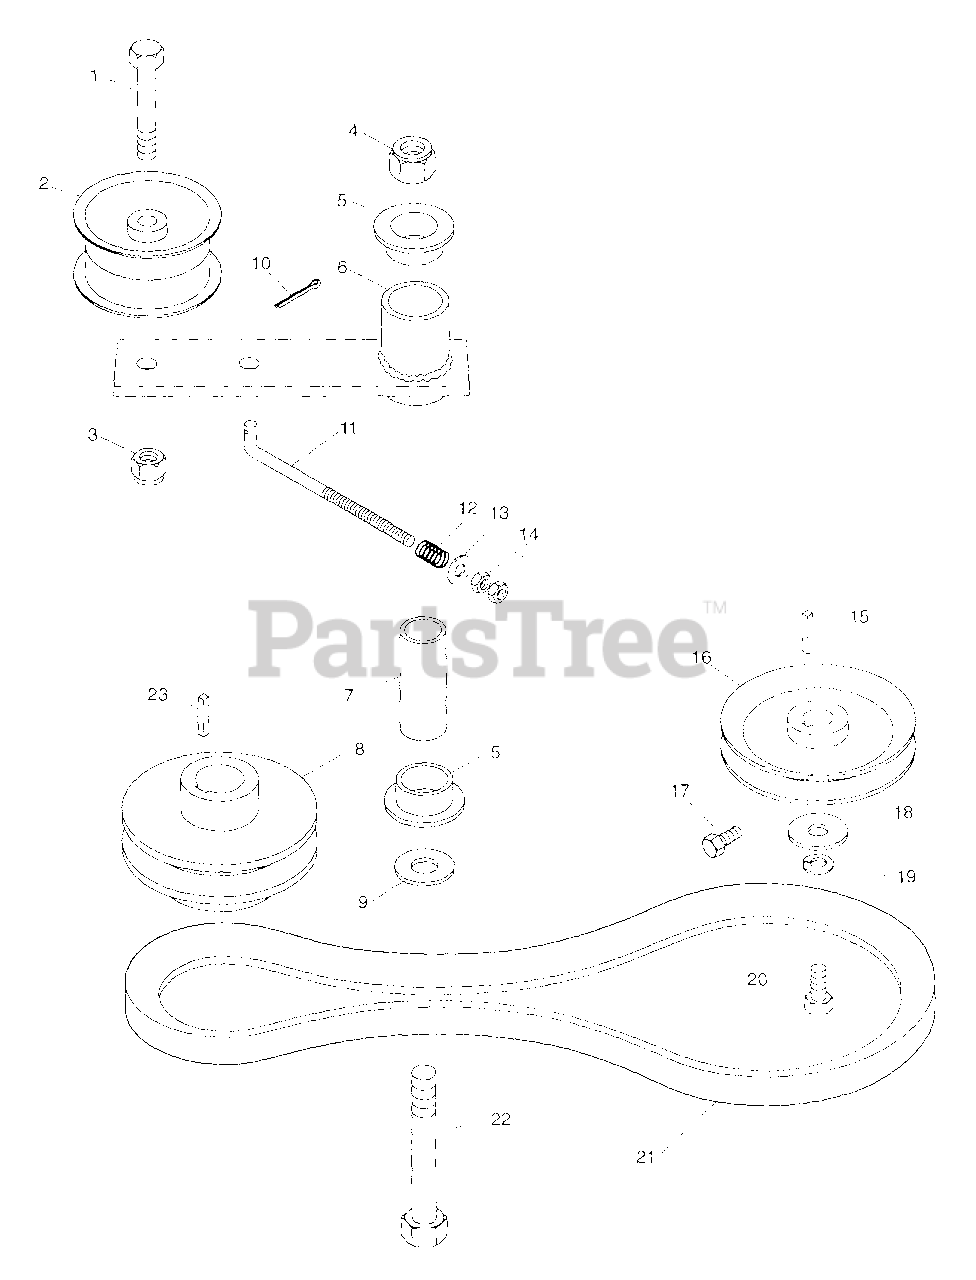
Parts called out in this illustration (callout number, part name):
1	Bolt-Hex .38-16 x 1.75 Grade 5
2	Idler - Pully Flat 3.25 x .625
3	Nut-Locking-Nylon .375-16 Grade 2
4	Nut-Locking-Nylon .50-13 Grade 2
5	Bushing-Flange .762 x 1.0 x .580 x 1.48
6	Weldment, Ground Drive Idler
7	Bushing, Steel .560 x .745 x 2.04
8	Pulley-V 4.00 x 1.125 w/Key
9	Washer-Flat-Steel .531 x 1.062 x .095
10	Pin-Cotter .09 x .75
11	Rod, Idler 11.0 Large
12	Spring-Compression .125 x .78 x 1.00
13	Washer-Flat-Steel .406 x .812 x .065
14	Nut-Hex .375 x 24 Grade 2
15	Key-Straight 5mm x 25mm x 5mm
16	Sheave, 4.0 x .199
17	Bolt-Hex .25 x 20 x .50 Grade 5
18	Washer-Flat-Steel .281 x 1.250 x .062
19	Washer-Lock .250 Regular
20	Bolt-Hex M6 x 1.0 12 MM Large
21	V-Belt A-RMA 28.22 x 33/64
22	Bolt-Hex .50 - 13 x 3.00
23	Key-Square .25 x 1.00 x .25
